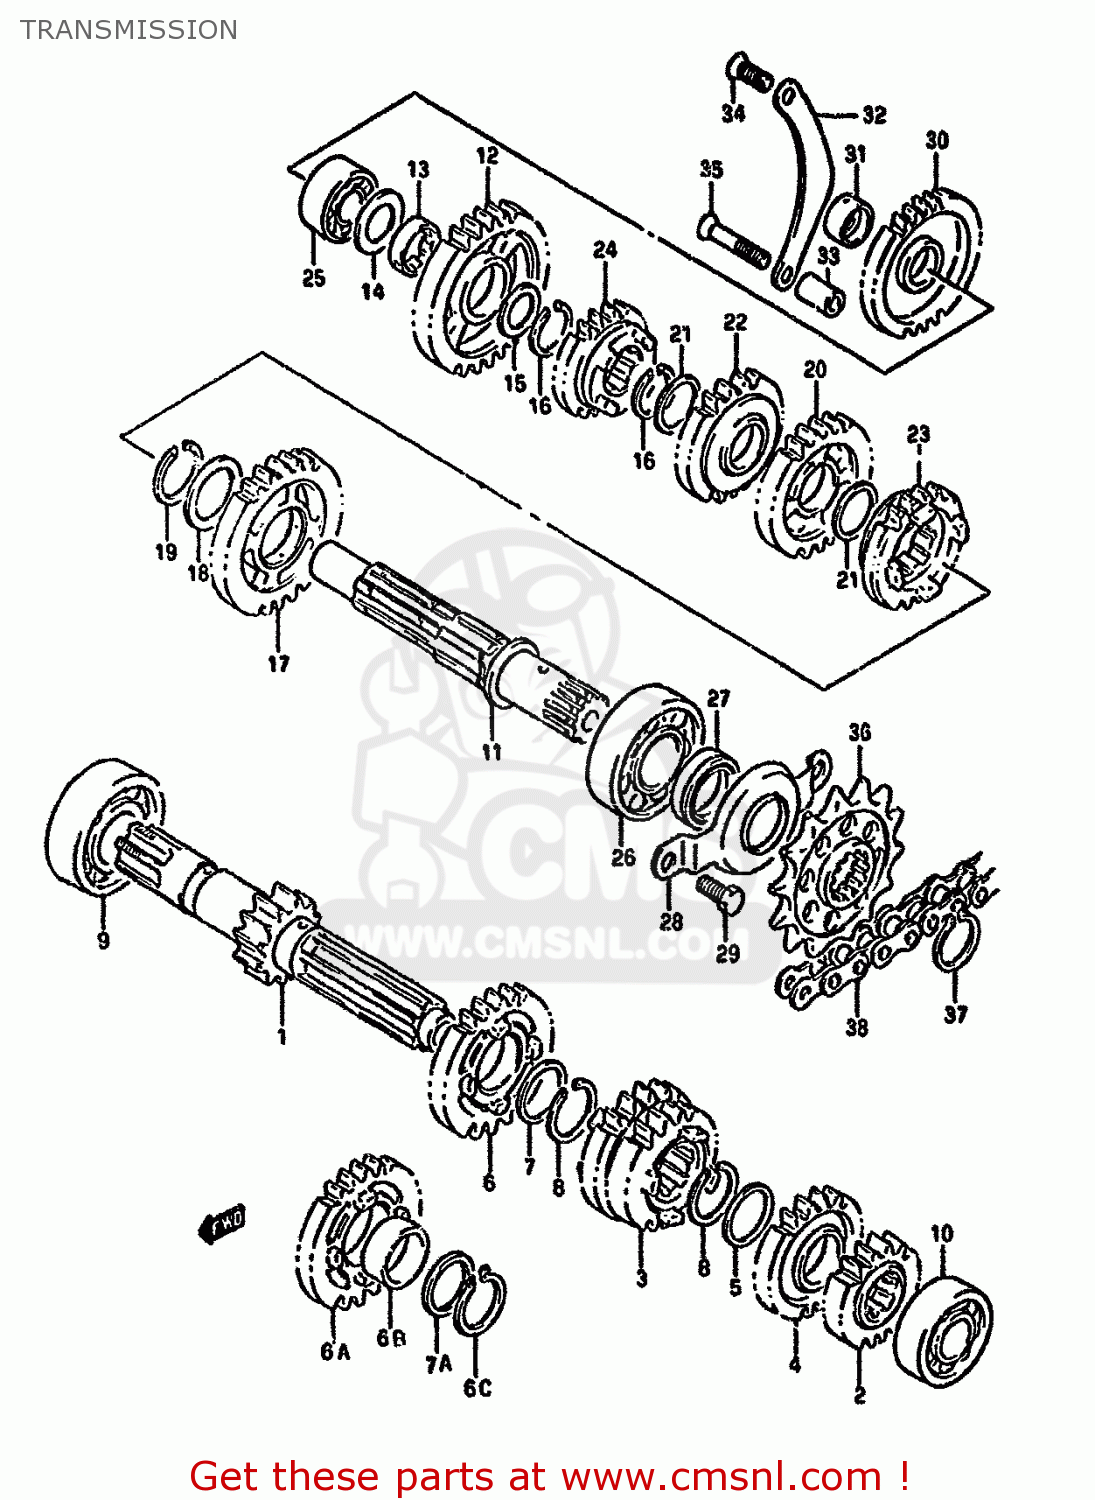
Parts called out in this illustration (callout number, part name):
1	SHAFT,COUNTER
2	GEAR,SECOND DRIVE (NT:15)
3	GEAR,3RD & 4TH DRIVE(NT:18/18)
4	GEAR,5TH DRIVE(NT:21)
5	WASHER
6	GEAR COMP,SIXTH DRIVE
6A	GEAR,6TH DRIVE(NT:23)
6B	BUSH(22X26X9)
6C	CIRCLIP
7	SHIM
7A	WASHER,THRUST
8	CIRCLIP
9	BEARING
10	BEARING
11	SHAFT,DRIVE
12	GEAR,FIRST DRIVEN (NT:29)
13	BUSH,1ST DRIVEN GEAR
14	WASHER
15	WASHER,THRUST
16	CIRCLIP
17	GEAR,2ND DRIVEN(NT:26)
18	WASHER
19	CIRCLIP
20	GEAR,3RD DRIVEN(NT:24)
21	SHIM
22	GEAR,4TH DRIVEN(NT:20)
23	GEAR,FIFTH DRIVEN (NT:20)
24	GEAR,6TH DRIVEN(NT:19)
25	BEARING(17X40X17.5)
26	BEARING(22X56X16)
27	SEAL,OIL(22X34X7)
28	RETAINER,DRIVE SHAFT OIL SEAL
29	BOLT
30	GEAR,KICK STARTER IDLE(NT:27)
31	BUSH,KICK STARTER IDLE GEAR
32	RETAINER,KICK IDLE GEAR
33	SPACER (6.5X12X21)
34	SCREW
35	SCREW
36	SPROCKET,ENGINE
37	CIRCLIP
38	CHAIN ASSEMBLY,DRIVE
